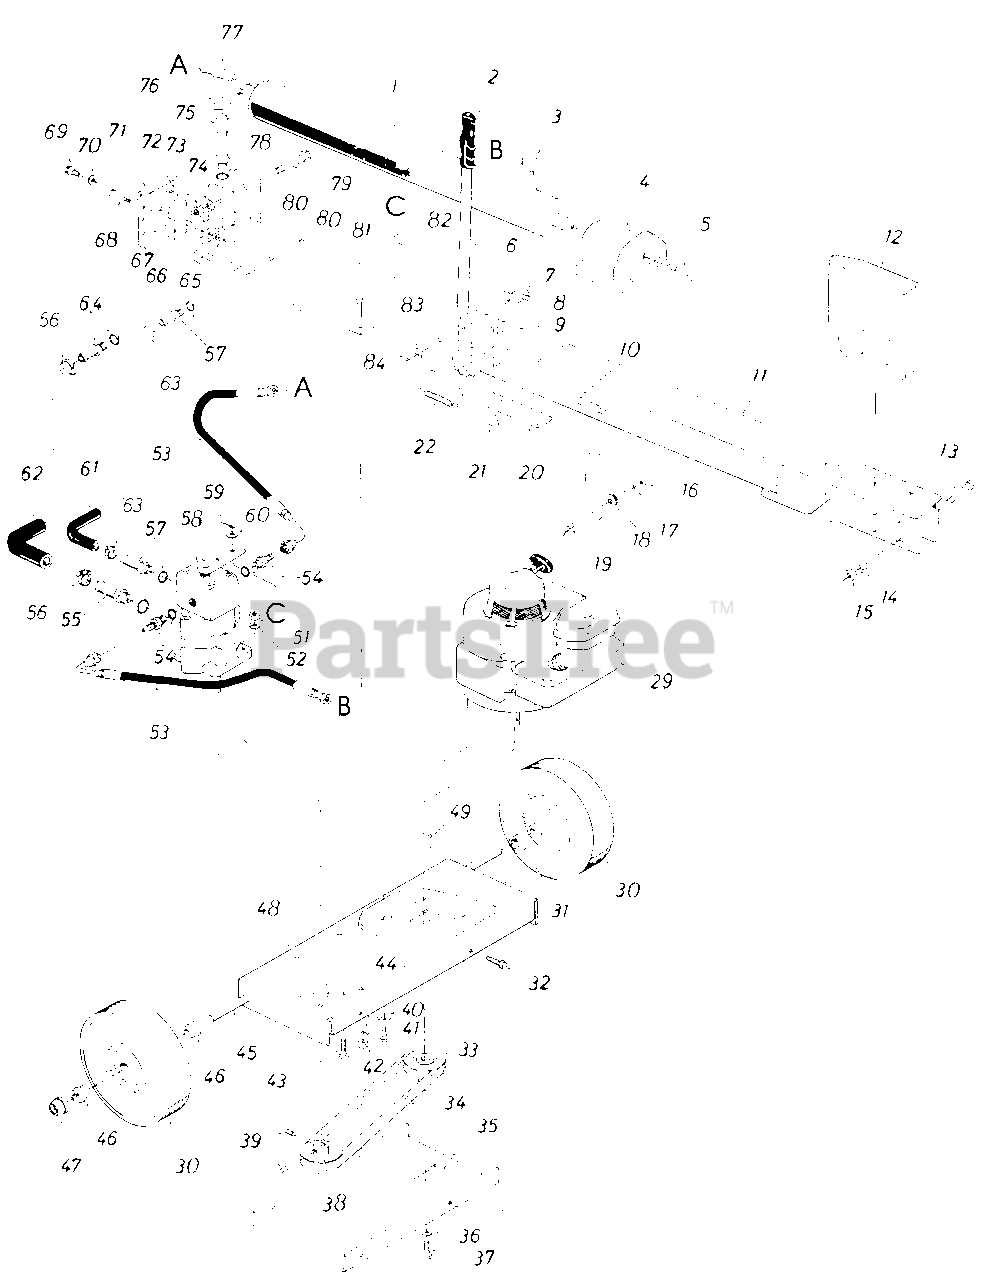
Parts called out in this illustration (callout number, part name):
1	2-1/2" Cylinder Ass'y. Comp.
2	Grip
3	90ø Elbow Adapter
4	Pusher Plate
5	Shoulder Bolt 5/8" Dia. x .660" Lg. 1/2-13 Thd.
6	Engagement Handle
7	Adjustment Ferrule
8	Hex Nut 5/16-18 Thd.*
9	L.-Wash. 5/16" I.D.*
10	Strainer Tube Ass'y.
11	Oil Tank Ass'y. Comp
12	Wedge Ass'y.
13	Hex Bolt 5/8-18 x 3.50" Lg. ( Grade 5)
14	L.-Wash. 5/8" I.D.
15	Hex Nut 5/8-18 Thd.*
16	Hex Nut 3/8-16 Thd.*
17	L.-Wash. 3/8" I.D.*
18	Rubber Wash.
19	Shoulder Bolt .498x .340
20	Engagement Brkt.
21	Shoulder Bolt .437" Dia. x.180" Lg.
22	Extension Spring .50" O.D. x 4. 25" Lg.
29	Engine - B & S
30	Wheel Ass'y. Comp. 10.0" x 2.75
31	Sleeve .532" i.C. x 875" O.D. x.90" Lg.
32	Hex Wash. Hd. Self Tap. Scr. 1/4-20 x .50" Lg.
33	1/2" V-Pulley 7/8" I.D. x 7/8" I.D. x 3-1/4" O.D.
34	"V"-Belt (4L) 1/2" V x 30" Lg.
35	Belt Cover
36	L.-Wash. 5/16" I.D.*
37	Hex Bolt 3/8-24 x 1.0" Lg.*
38	1/2 (4L) "V"-Pulley 5/8" I.D. x 3-1/2" O.D.
39	Set Scr. 1/4-28 x .25" Lg.
40	Bell.-Wash..40" I.D. x .88"O.D.
41	Hex Wash. Hd. TT-Tap Scr. 3/8-16 x .87" Lg.
42	Hex Nut 5/16-24 Thd.*
43	Hex Bolt 5/16-18 x 1.00" Lg.*
44	L.-Wash. 5/16" I.D."
45	Axle Shaft 5/8 "Dia. x 25.5" Lg.
46	FlangeBrg.w/Flats .631" I.D.
47	Push Cap 5/8" Dia. Rod
48	Frame- Engine
49	Sq. Key 3/16" x 3/16" x 1.50" Lg.*
51	Hex Nut 5/16-18 Thd.*
52	L.-\l'lash. 5/16" I.D.*
53	High Pressure Hose
54	Adapter - or Boss to MJIC 9/16-18 to 7/16-20
55	Adapter 3/4" Tubing to 3/4 -16 M-Boss
56	Hose Clamp 5/8" 1. D .
57	Adapter 1/2" Tube 9/16-18 or M-Boss
58	Valve Ass'y.
59	Cotter Pin 3/32" Dia. x .75" Lg.*
60	F l.-Wash. 344" 1. D . x .62" O.D. x .063
61	Return Hose.50" I.D.
62	Suction Hose.75" I.D.
63	Hose Clamp 1/4" I.D.
64	Adapter 1.0" Tube 1-1/16- 12 "O"-Ring
65	Hex Nut 5/16-18 Thd.*
66	L.-Wash. 5/16" I.D.*
67	Fl.-Wash. .343" I.D. x .687" O.D. x .062
68	Hex Bolt 5/16-18 x 1.50" Lg.*
69	H ex H d. Tap Scr. 5/16 "
70	Gasket
71	End Plate
72	Gasket
73	Hex ut 3/4" Thd.*
74	L.-Wash. 3/4" I.D.*
75	Filler Tube Ass'y.
76	Oil Fill Cap
77	45ø Male Adapter 7/16-20 MJ-1/4-18 NP
78	"O"-Ring .92" I.D. x 1.16" O.D. x .116 Dia.
79	Hex Bolt 3/4" x 4.0" Lg.
80	Hex Nut 11/16-1 Thd.
81	Hex Bolt 5/16-24x 1.00" Lg. ( Grade 5)
82	Engagement Rod 16.75" Lg.
83	Fl.-Wash. .344" I.D. x .62" O.D. x .063
84	Hair Pin Cotter 5/16" Dia.
